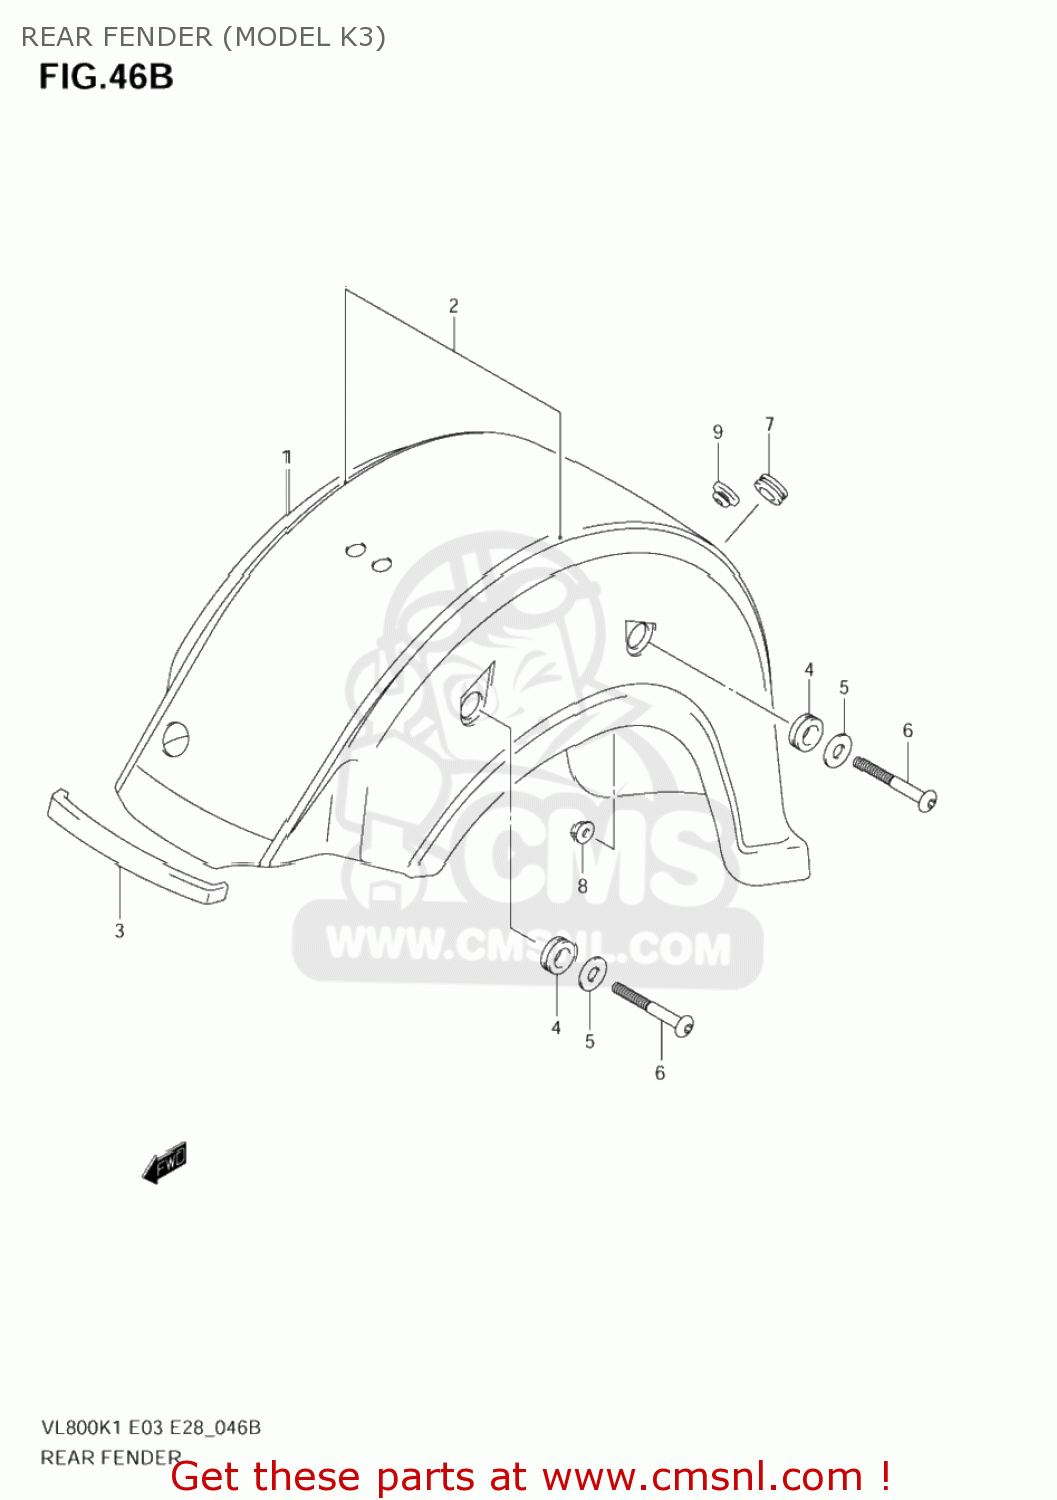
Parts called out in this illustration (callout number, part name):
1	FENDER,RR
2	TAPE SET,RR FENDER
3	SEALER,SIDE COVER L
4	CUSHION,FRAME COVER UPR RR
5	WASHER(15.5X26X2.3)
6	BOLT,RR FENDER
7	CUSHION
8	NUT
9	CUSHION
